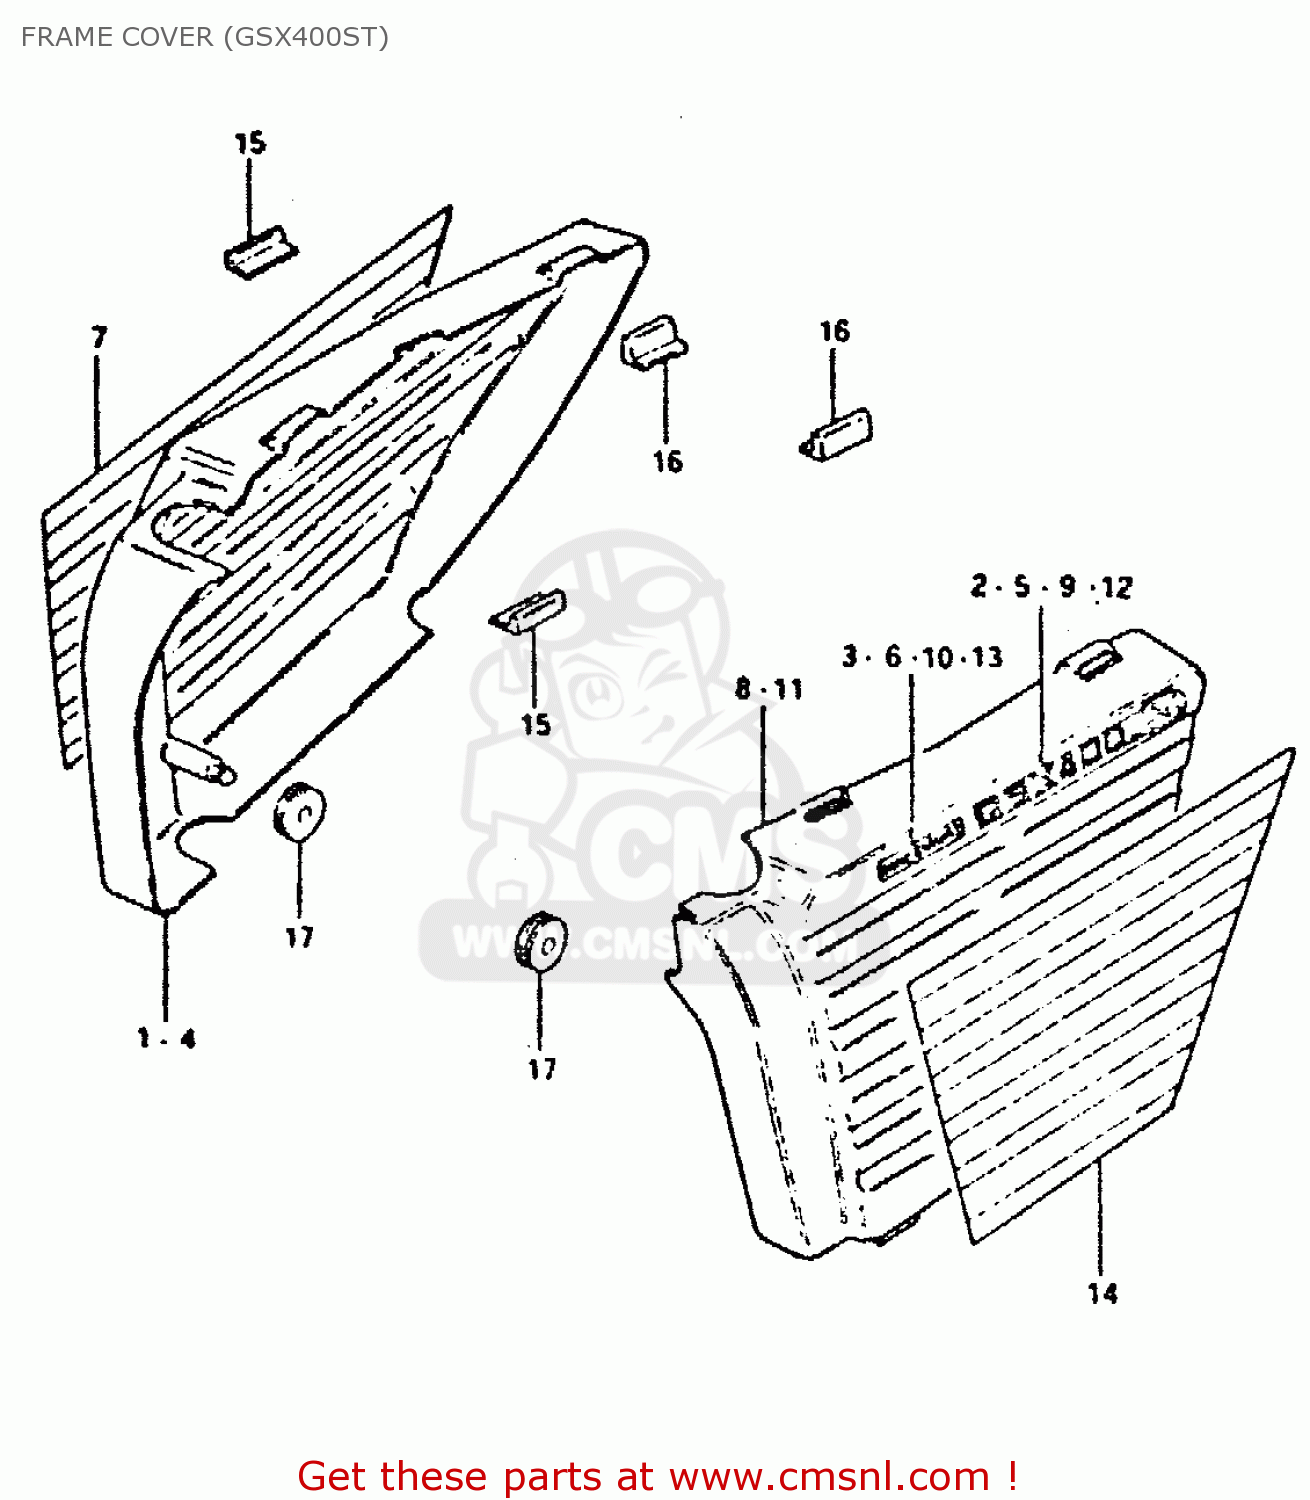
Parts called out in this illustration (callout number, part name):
1	COVER,FRAME,RIGHT
2	EMBLEM, "GSX400S"
3	EMBLEM (WHITE)
4	COVER,FRAME,RIGHT
5	EMBLEM, "GSX400S"
6	EMBLEM (BLACK)
7	TAPE SET, RH
8	COVER,FRAME,LEFT
9	EMBLEM, "GSX400S"
10	EMBLEM (WHITE)
11	COVER,FRAME,LEFT
12	EMBLEM, "GSX400S"
13	EMBLEM (BLACK)
14	TAPE SET
15	CUSHION,FRAME COVER
16	CUSHION,FRAME COVER
17	CUSHION
